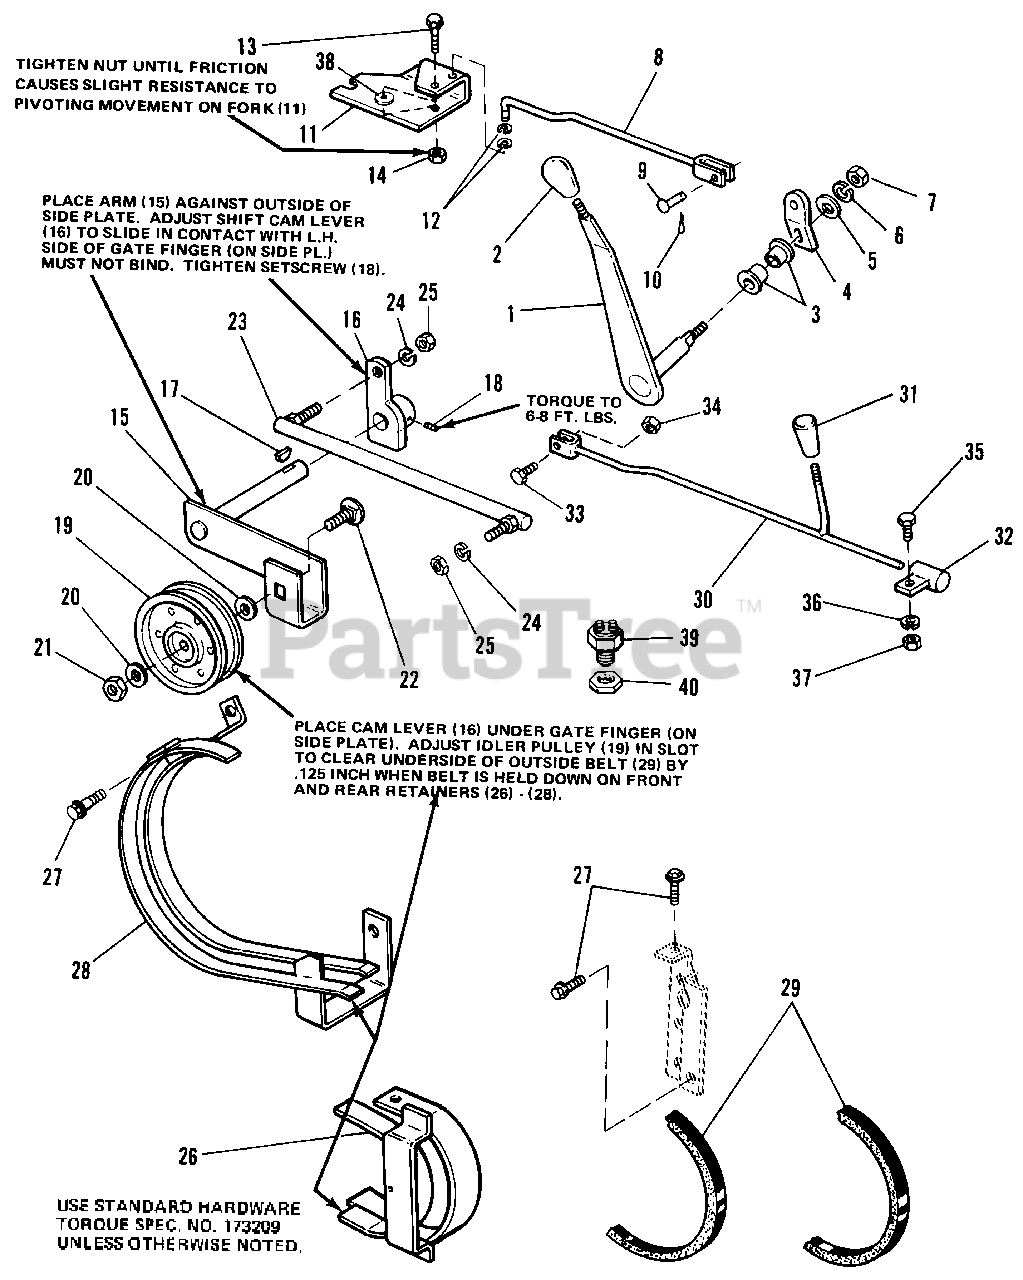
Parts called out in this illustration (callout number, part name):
1	CONTROL LEVER ASSEMBLY
2	KNOB
3	BUSHING, Flanged
5	WASHER, 3/8
6	LOCKWASHER, 3/8
7	NUT, Hex Full, 3/8-16
8	CONTROL ROD ASSEMBLY
10	PIN, Cotter, 3/32 x 3/4
11	FORK, Shift
13	CAPSCREW, Hex Hd., 3/8-16 x 2
14	LOCKNUT, Hex, 3/8-16
15	IDLER ARM ASSEMBLY
16	CAM SHIFT LEVER ASSEMBLY
17	KEY, Woodruff, No. 5 1/8 x 5/8
18	SETSCREW, Sq. Hd., 1/4-20 x 1/4
19	PULLEY (Idler)
20	WASHER, 5/16
21	LOCKNUT, Hex, 3/8-16
22	BOLT, Carriage, 3/8-16 x 1-1/4
23	JOINT, Ball, Dbl. End
24	LOCKWASHER, 5/16
25	NUT, Hex, Full, 5/16-24
26	BELT RETAINER ASSY
27	SCREW, Taptite, 5/16-18 x 1/2
28	REAR RETAINER ASSY (Mfg. No. 1690203) REAR RETAINER ASSY (Mfg. No. 1690204)
30	SHIFT ROD ASSY
31	HANDLE, Shift Rod
32	SHIFT ROD GUIDE ASSY
33	CAPSCREW, Hex Hd,, 5/16-18 x 1-1/2
34	NUT, Hex, Full, 5/16-18
35	CAPSCREW, Hex Hd., 1/4-20 x 5/8
36	LOCKWASHER, 1/4
37	NUT, Hex, Full, 1/4-20
39	SWITCH, Interlock
40	NUT, Pal
